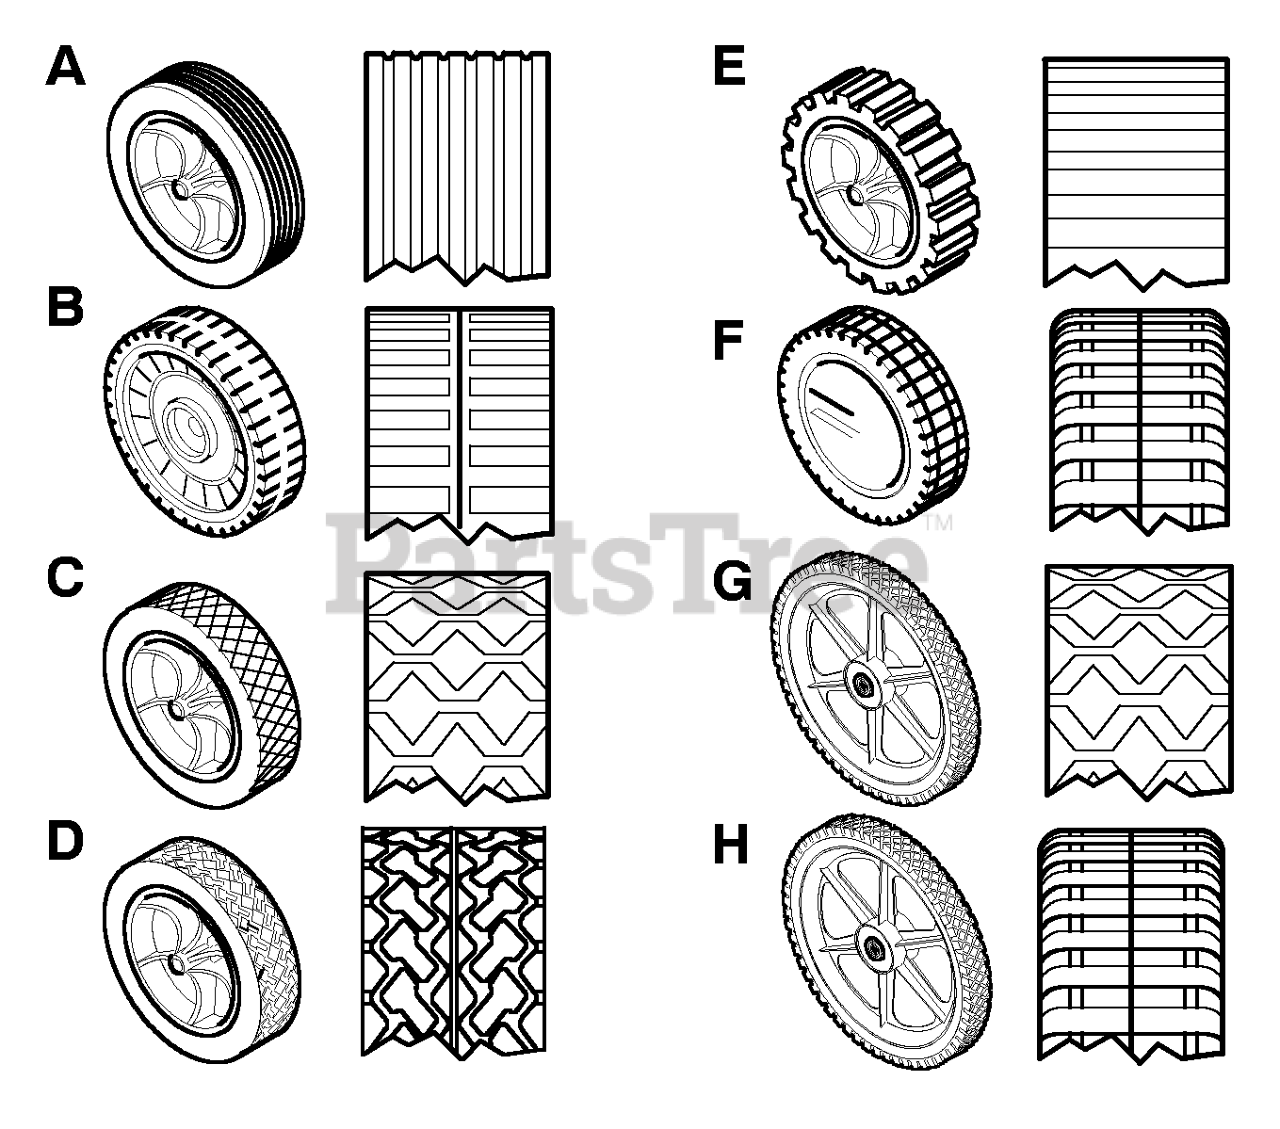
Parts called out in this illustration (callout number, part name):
A	WHEEL & TIRE ASSEMBLY, Light Gray, 8"
A	8-inch Plastic, Dark Gray
A	8-inch Metal, White
B	7-inch Plastic, White
B	7-inch Plastic, Light Gray
B	7-inch Plastic, Dark Gray
C	6-inch Plastic, White
C	7-inch Plastic, White
C	7-inch Plastic, Light Gray
C	7-inch Plastic, Dark Gray
C	8-inch Plastic, White
C	8-inch Plastic, Light Gray
C	8-inch Plastic, Dark Gray
C	8-inch Metal, White
D	7-inch Plastic, White
D	WHEEL & TIRE ASSEMBLY, White, 8"
D	8-inch Plastic, Light Gray
D	8-inch Plastic, Dark Gray
E	WHEEL & TIRE ASSEMBLY, White, 8"
E	8-inch Plastic, Dark Gray
E	8-inch Metal, White
F	WHEEL & TIRE ASSEMBLY, White, 8"
F	8-inch Plastic, Light Gray
F	8-inch Plastic, Dark Gray
F	8-inch Ball Bearing, Light Gray
F	8-inch Ball Bearing, Dark Gray
G	14-inch, White
G	14-inch, Light Gray
G	14-inch, Dark Gray
G	WHEEL & TIRE ASSEMBLY, White, 14"
G	14-in, Ball Bearing, Light Gray
G	14-in, Ball Bearing, Dark Gray
H	14-inch, White
H	14-inch, Light Gray
H	14-inch, Dark Gray
H	WHEEL & TIRE ASSEMBLY, Ball Bearing, 14"
H	14-in, Ball Bearing, Light Gray
H	14-in, Ball Bearing, Dark Gray
